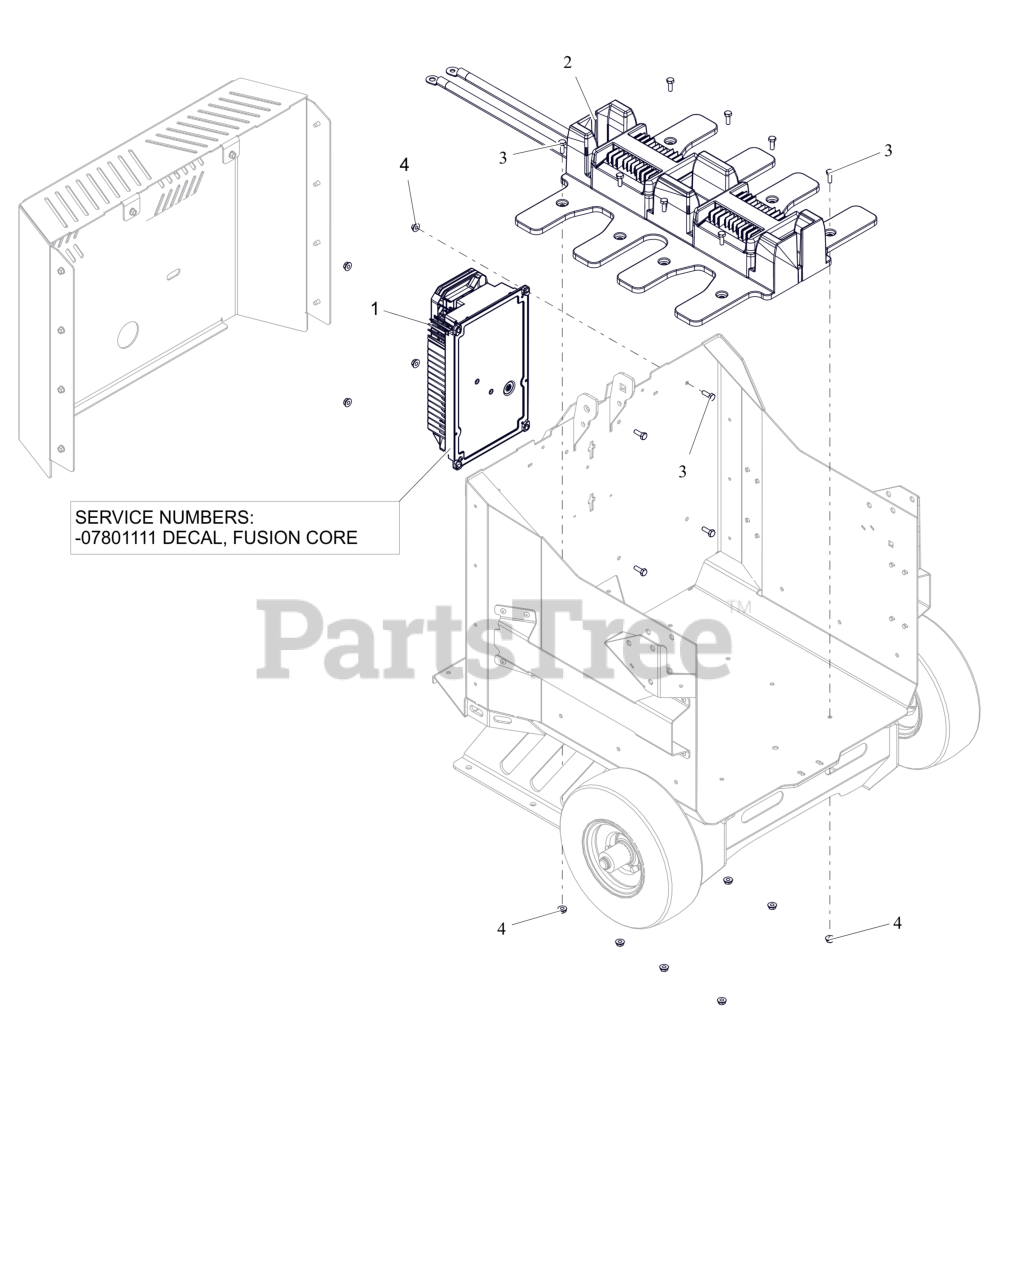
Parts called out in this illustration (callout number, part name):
1	CHARGER, BATTERY DELTA-Q
1	DECAL, FUSION CORE
2	BASE, BATTERY BUSSBAR
3	BLT, HEX .25-20X.75 G5 ZCC
4	NUT-LK-CTR-FLG .25-20 ZC120
